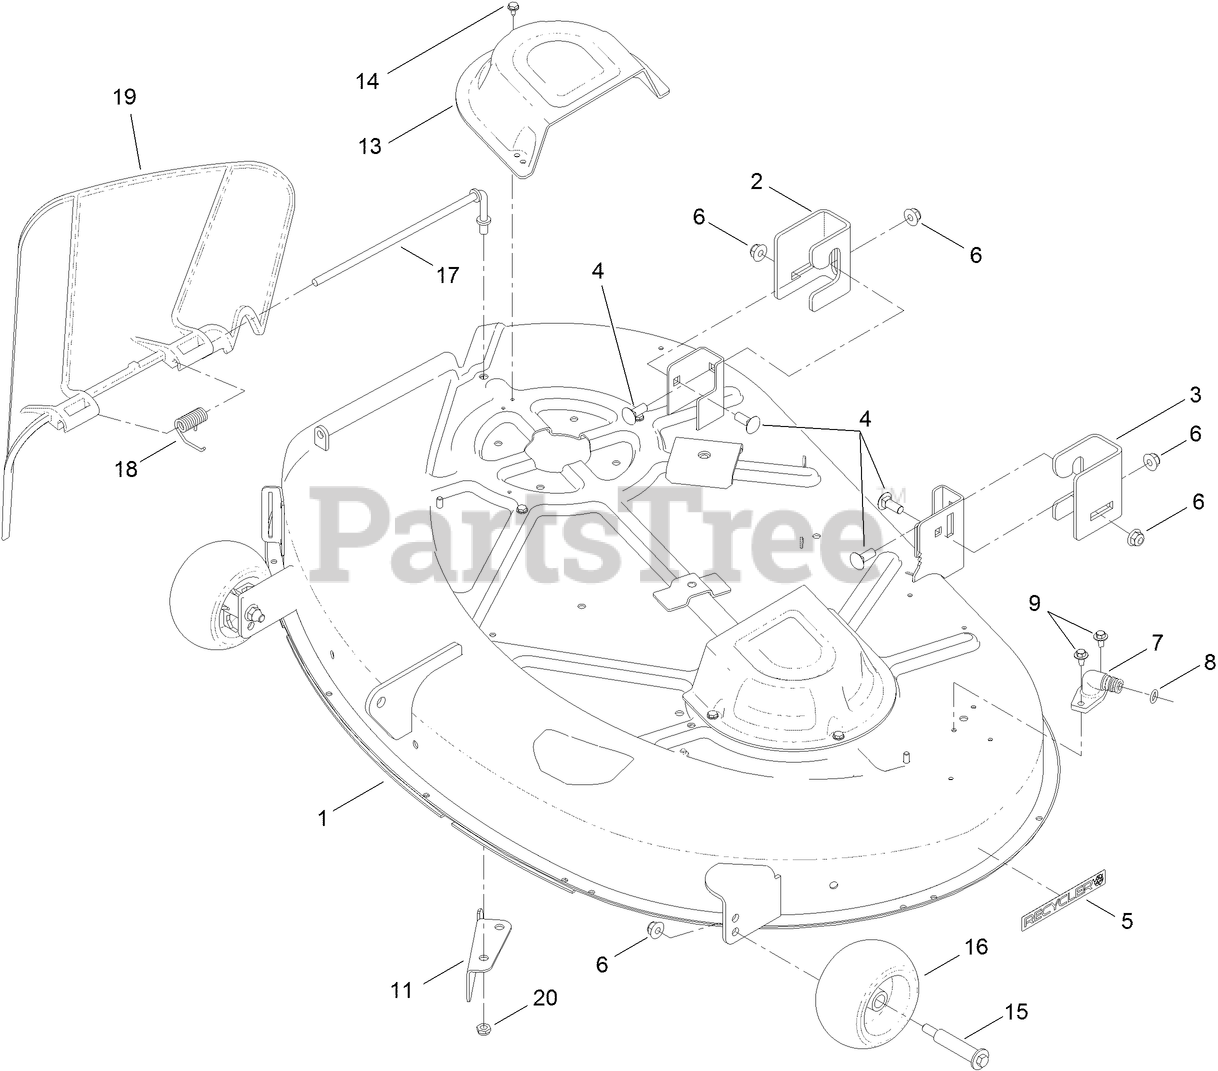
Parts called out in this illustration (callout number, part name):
1	42 INCH DECK AND DECAL ASM
3	BRACKET-HANGER, LH
4	BOLT-CARR
5	DECAL-RECYCLER
6	NUT-HF, NI
8	O-RING
9	SCREW-HHFTF
11	BAFFLE-CUTOFF
13	COVER-BELT
14	SCREW-HWHTF
15	BOLT-SHOULDER
16	ROLLER-SCALP, ANTI
17	ROD-PIVOT
18	SPRING-TORSION
19	DEFLECTOR
